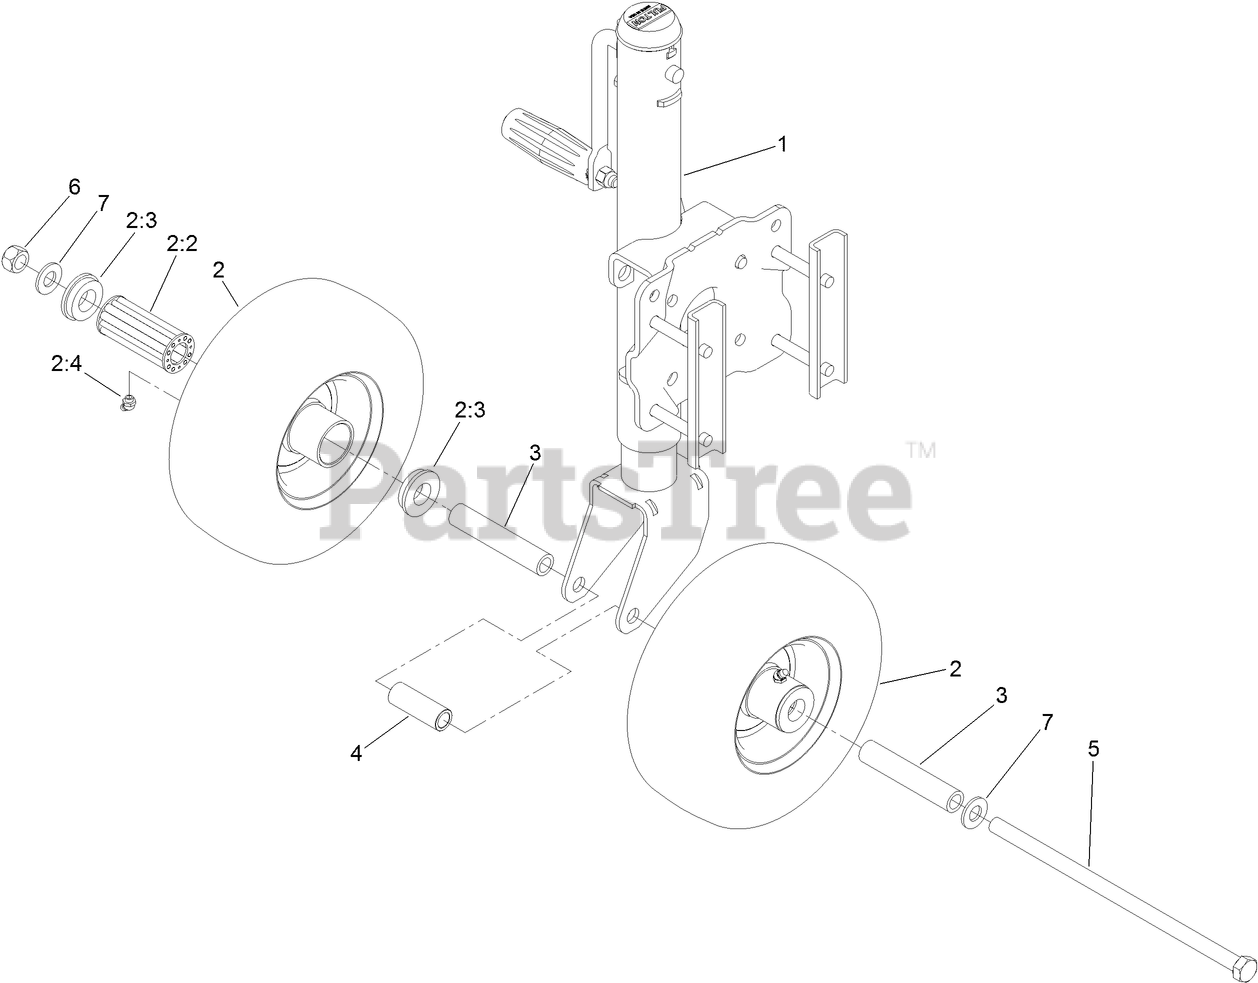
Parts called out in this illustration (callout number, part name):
1	JACK-TRAILER
2	WHEEL AND TIRE ASM
2:2	BEARING-ROLLER
2:3	BUSHING
2:4	FITTING-GREASE
3	BUSHING-SPANNER
4	SPACER
5	SCREW-HH
6	NUT-HEX
7	WASHER-FLAT
